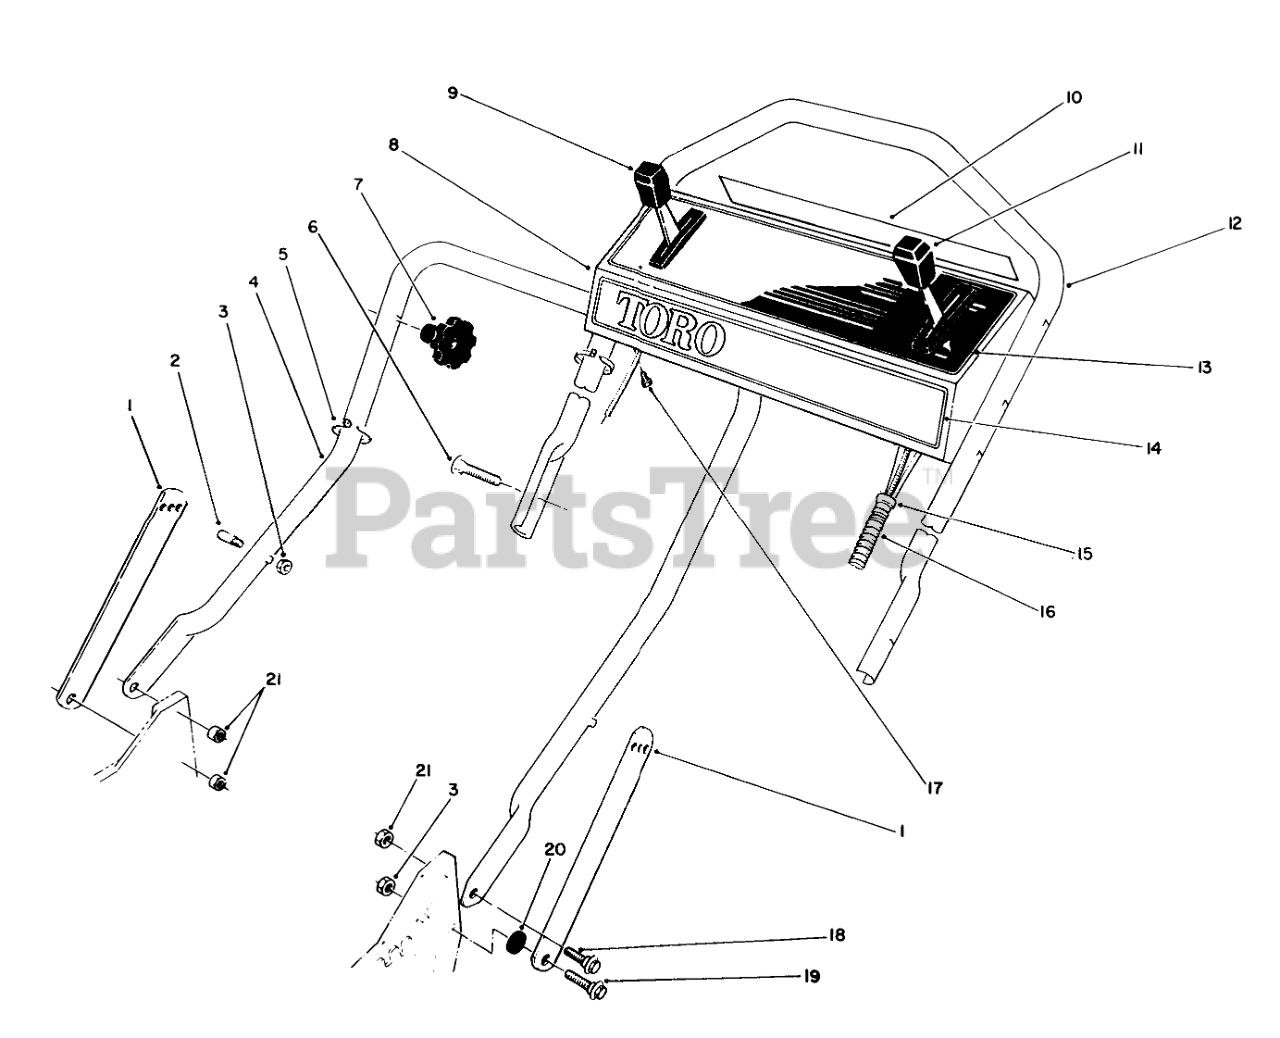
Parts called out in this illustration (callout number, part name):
1	Handle Latch
2	HANDLE PIN
3	NUT-LOCK, NI
4	LOWER HANDLE ASM
5	TIE-CABLE
6	5/16-18 X 2 HNDLE SCREW
8	Panel-Control (Incl. Ref. #10 & 13)
9	GROUND SPEED CONTROL
10	DECAL - PANEL, REAR
11	THROTTLE CONTROL
12	Handle-Upper
13	Decal-Instruction
14	DECAL - TORO PANEL
15	FITTING-RING
16	CONTROL CABLE COVER
17	SCREW-HWHTF
18	SCREW-SHOULDER
19	SCREW-SHOULDER
20	SPACER
21	NUT-LOCK, NI
